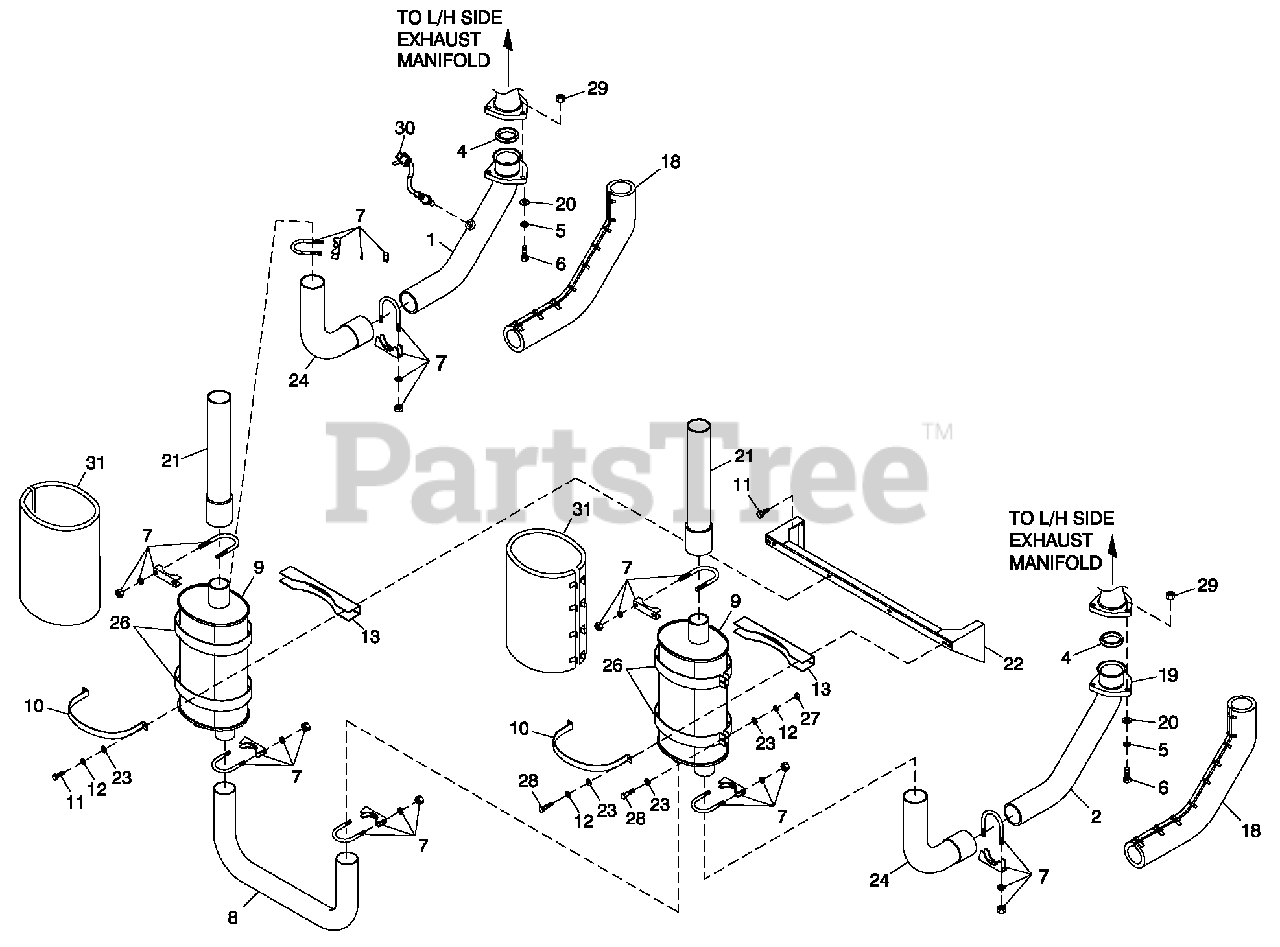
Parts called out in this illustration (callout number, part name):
1	PIPE EXH MAN R/H 6.8L G/B CPL (6.8L C5)
2	PIPE EXH MAN L/H 6.8L G/B CPL (6.8L C5)
4	RING GAS KET 2.5 DIA
5	WASHER LOCK M10S S
6	SCREW HHC M10-1.5 X 50 SS FTH
7	BOLT U 3/8-16X2.62
8	PIPE EXHAUS T CROS S OVER
9	MFLR 7" X 9" X 25" (2) 2.5" IN/2.5" OUT
10	MUFFLER STRAP
11	SCREW THF M6-1 X 16 N WA Z/JS
12	WASHER LOCK M6-1/4
13	MUFFLER BRACKET STIFFENER
18	EXHAUST BLANKET 900MM LONG (6.8L C5)
19	FLANGE EXHAUST
20	WASHER FLAT 3/8 SS
21	EXHUAST OUTLET PIPE CPL
22	BRKT MUFFLER
23	WASHER FLAT 1/4-M6 ZINC
24	PIPE ELBOW EXHAUS T MUFFLER
26	MUFFLER STRAP UPPER/LOWER
27	NUT HEX M6X 1.0 G8YEL CHR
28	SCREW HHC M6-1.0 X 35 G8.8 BLK
29	NUTHEXM10-1.5S S
30	SENS OR OXYGEN
31	BLANKET EXHAUST MUFFLER 584MM
